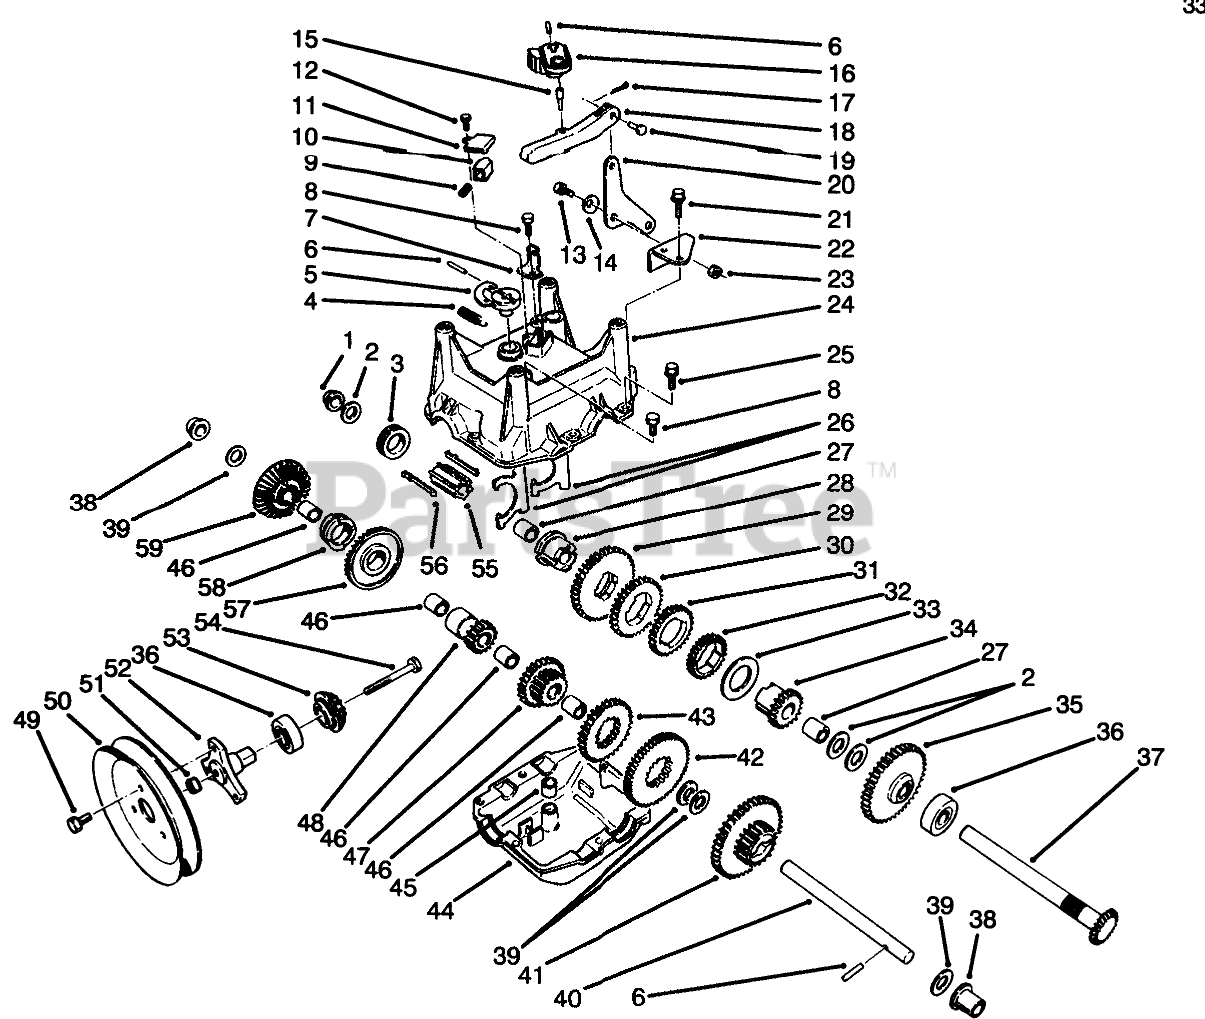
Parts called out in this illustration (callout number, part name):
1	BUSHING-FLANGE, OUTPUT
2	BEARING-THRUST
3	COLLAR-SHIFT
4	SPRING-EXTENSION
5	LEVER
6	PIN-SPRING
7	BRACKET-CABLE
8	SCREW-HWH
9	SPRING-DETENT
10	BUTTON-DETENT
11	COVER-DETENT
12	SCREW-HWH
13	SCREW-SHOULDER
14	WASHER-CURVED
15	PIN-LINK, GEAR SHIFT
16	LEVER-SHIFT, GEAR
17	PIN-COTTER
18	LINK-SHIFT, GEAR
19	PIN-CLEVIS
20	BELLCRANK
21	SCREW-HWH
22	BRACKET-BELLCRANK
23	NUT-LOCK, NI
24	GEARCASE-UPPER, CASING
25	SCREW-HWHTF
26	YOKE-SHIFT
27	BUSHING-OUTPUT
28	SLEEVE-GEAR
29	GEAR-45 T
30	GEAR-34 T
31	GEAR-27 T
32	GEAR-29 T
33	WASHER-THRUST
34	GEAR-SLEEVE, 19 T
35	GEAR-41 T
36	BEARING-BALL
37	SHAFT-OUTPUT
38	BUSHING-INTERMEDIATE
39	WASHER-THRUST
40	SHAFT-INTERMEDIATE
41	GEAR-19/41 T
42	GEAR-51 T
43	GEAR-33 T
44	GEARCASE-LOWER, CASING
45	BUSHING-YOKE
46	Bushing-Output
47	GEAR-26 T
48	GEAR-BEVEL, 15 T
49	SCREW
50	TRACTION-SHEAVE, HALF
51	NUT-HHF
52	HUB-PULLEY
53	PINION-BEVEL
54	SCREW-HH
55	SLEEVE-SHIFT
56	KEY-SHIFT
57	GEAR-BEVEL, 36 T
58	COLLAR-SHIFT
59	Gear-Bevel Reverse 36T (Incl. Ref. #46)
